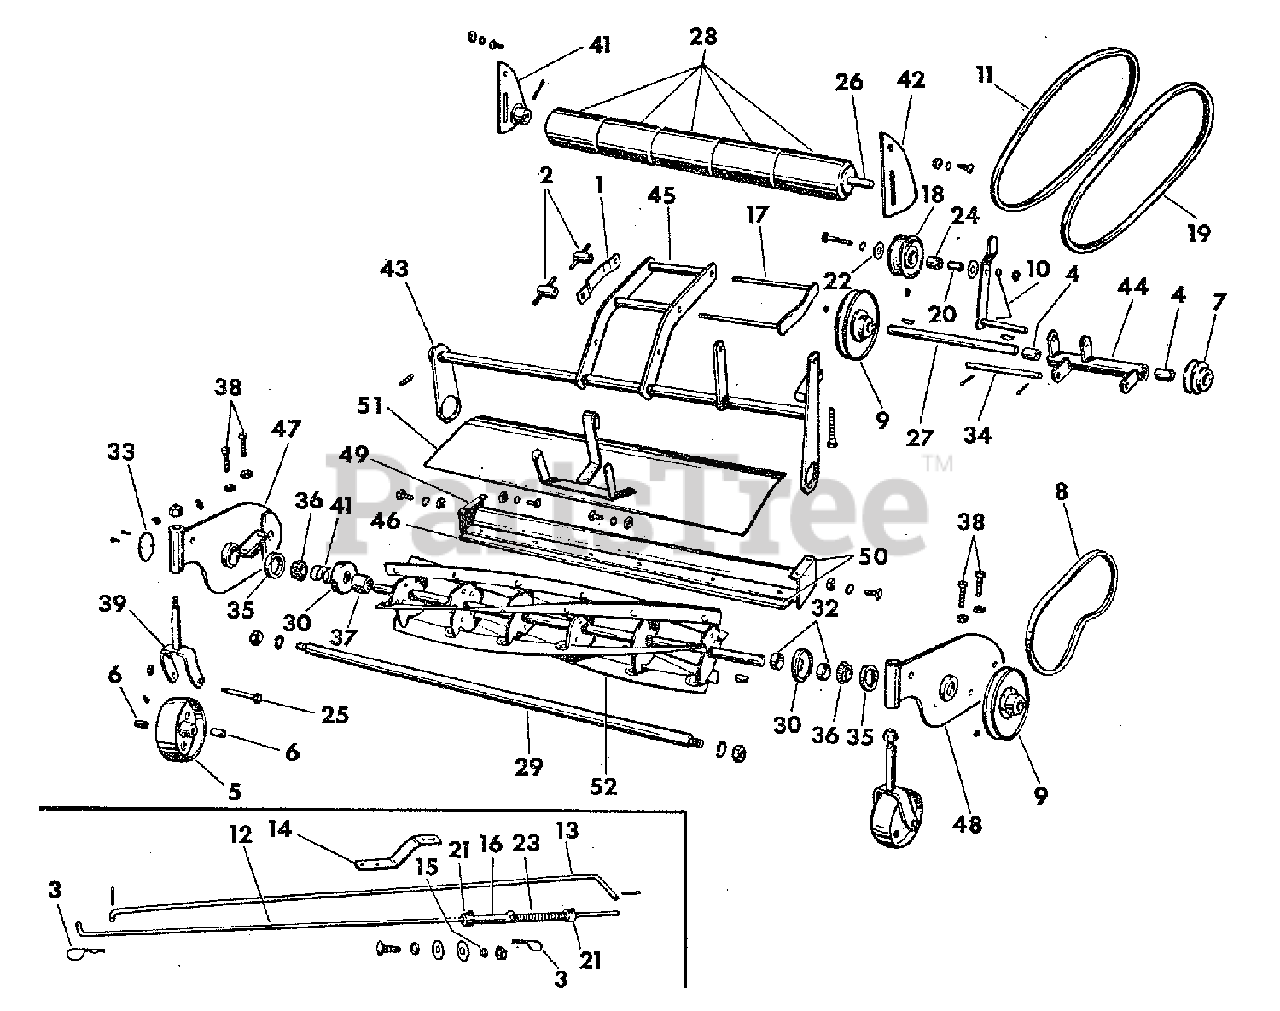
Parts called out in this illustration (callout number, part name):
1	SIDE PLATE, Hitch
2	NUT, Wing, Complete
3	CLIP, Spring
4	BUSHING, Bronze
5	CASTER WHEEL, w/Bearing and Grease Fitting
6	BEARING, Caster Wheel
7	SHEAVE, Wheel Driver
8	BELT, Reel Drive, 27" Circumferance
9	COUNTER SHAFT & REEL SHEAVE
10	HOLDER, Belt
11	BELT, 31" Circumferance, 1-1/2 HP
12	ROD, Lower Idler
13	ROD, Upper Idler
14	LEVER, Lower Clutch
16	ROD SOCKET ASSEMBLY
17	HITCH CLAMP ASSEMBLY
18	IDLER PULLEY
19	BELT, 35", 3HP
20	INNER BEARING RACE
21	COLLAR, Set
22	WASHER, Thrust
23	SPRING, Idler Rod
24	BEARING, idler Pulley
25	SPINDLE, Caster Wheel
26	ROLLER SHAFT
27	SHAFT, Transmission
28	HARD WOOD ROLLER
29	ROD, Spacer
30	COVER, Bearing
31	SPRING, Bearing
32	SPACER, Bearing, Short
33	CAP, Bearing
34	PIN, Hinge
35	CAP, Bearing
36	CONE, Bearing
37	SPACER, Bearing, Long
38	SCREW, Adjusting Blade
39	FORK ASSEMBLY, Caster
40	LEVER ASSEMBLY, Idler
41	BRACKET, Roller, R.H.
42	BRACKET, Roller, L.H.
43	PUSH ARM ASSEMBLY, R.H.
44	BEARING BRACKET, w/Bushings and Grease Fitting
45	PUSH ARM ASSEMBLY, w/L.H. Push Arm
47	LAWN MOWER FRAME ASSEMBLY, R.H.
48	LAWN MOWER FRAME ASSEMBLY, L.H.
49	CUTTER BAR ASSEMBLY
50	CUTTER BAR ASSEMBLY, w/Blade
51	GRASS GUARD ASSEMBLY
52	REEL ASSEMBLY, 24"
